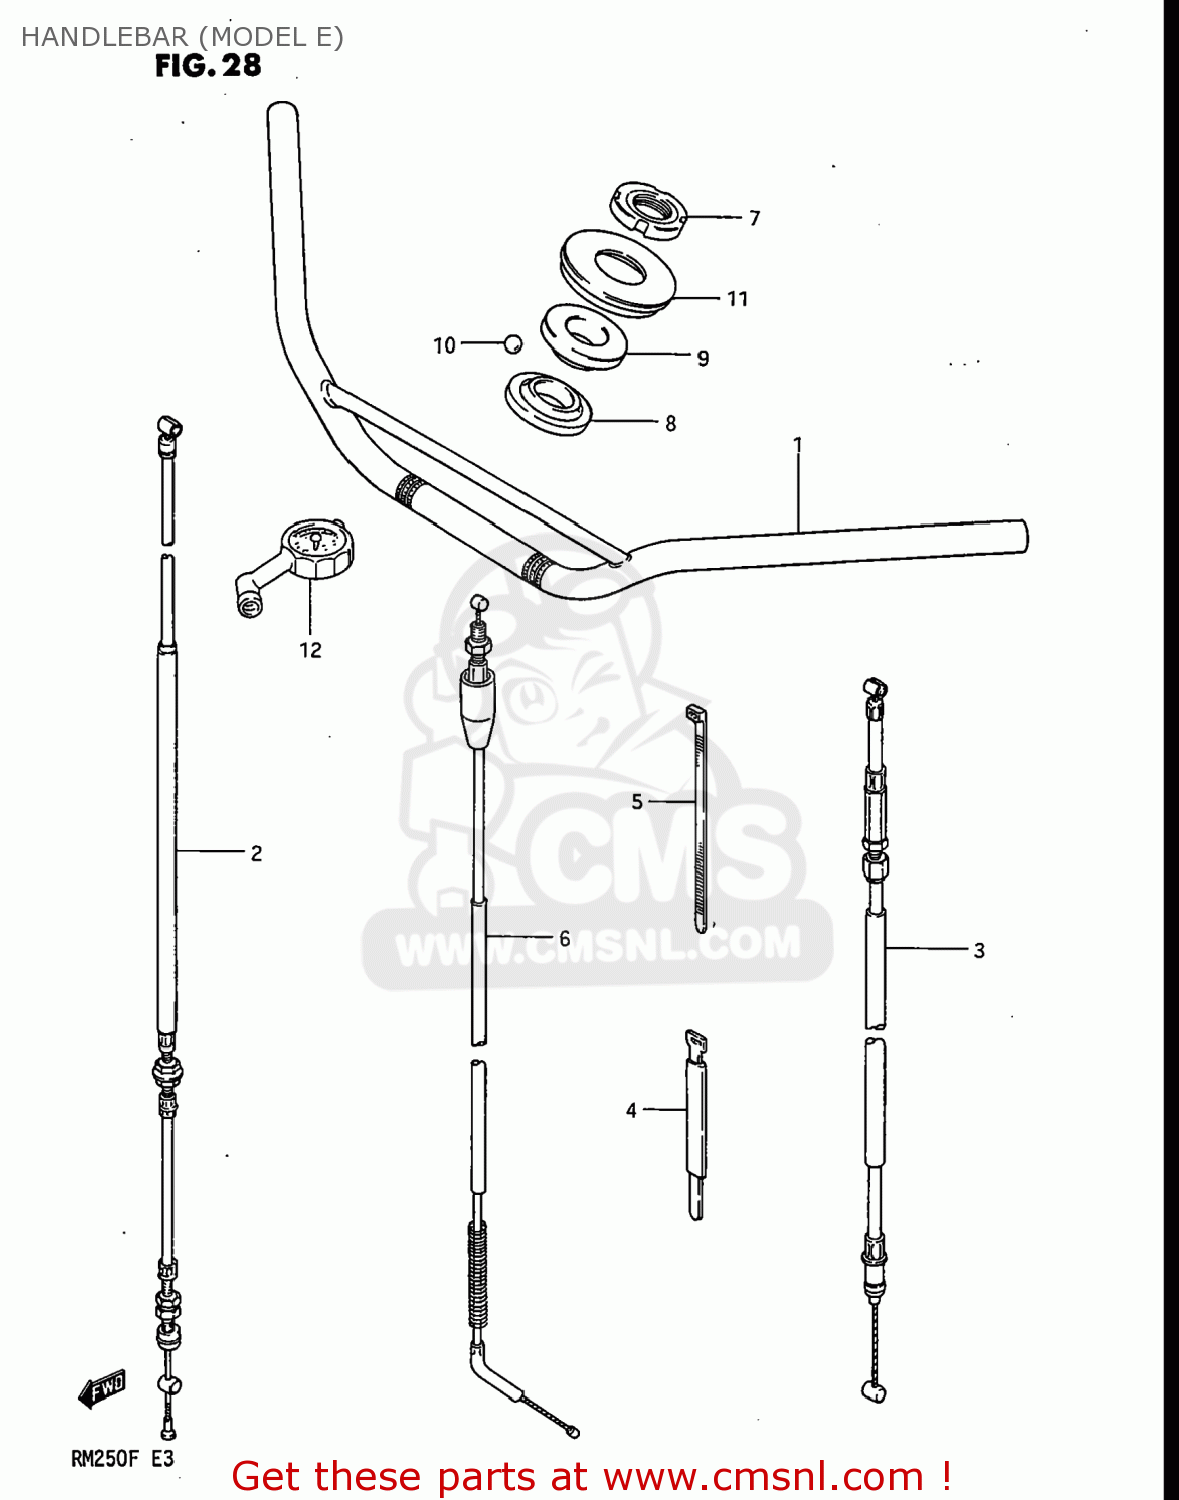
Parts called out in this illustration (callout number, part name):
1	HANDLEBAR
2	CABLE,FRONT BRAKE
3	CABLE ASSY,CLUTCH
4	CLAMP
5	CLAMP(L:235)
6	CABLE ASSEMBLY,THROTTLE
7	NUT,STEERING STEM
8	RACE,STEERING,INNER,UPPER
9	RACE,STEERING,OUTER,UPPER
10	BALL
11	SEAL,STEERING UPR DUST
12	GAUGE ASSY,AIR PRESSURE
